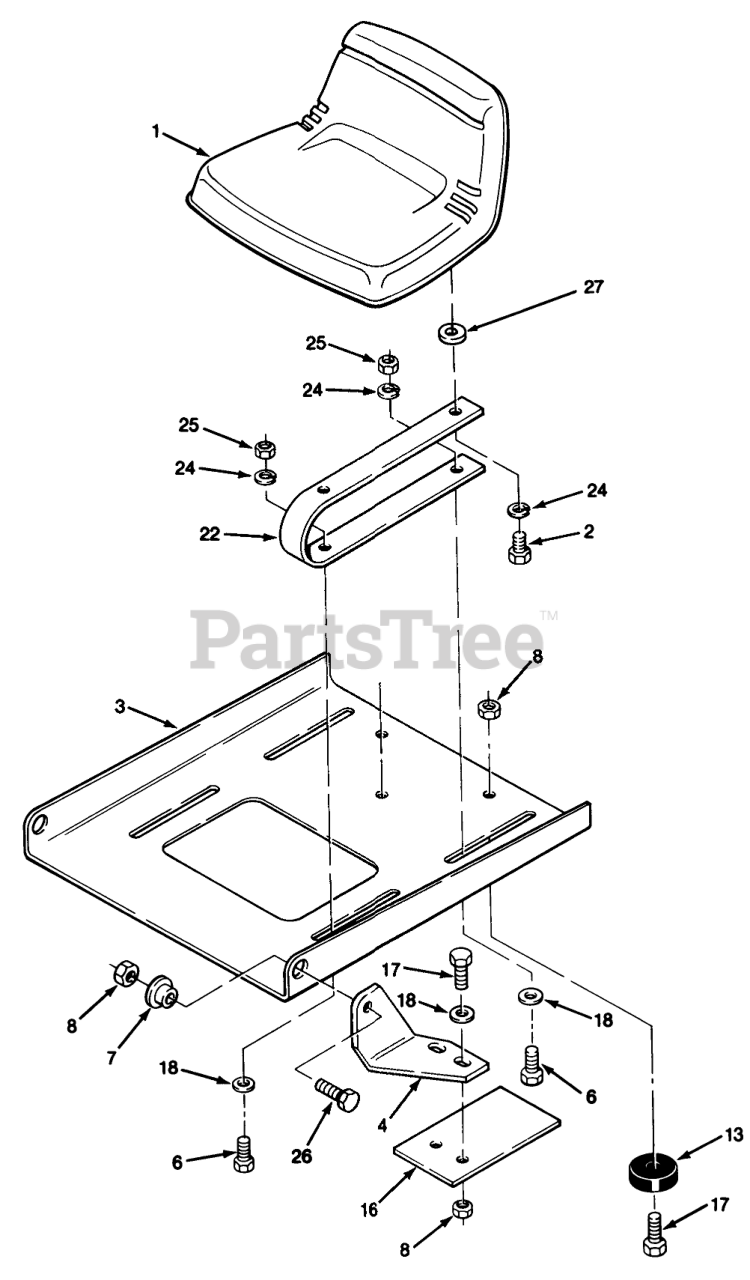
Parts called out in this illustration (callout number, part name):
1	SEAT V-510
2	SCREW-HH
3	PLATE-SEAT PIVOT B
4	BRACKET-PIVOT L.H B
6	SCREW-HH
7	BUSHING
8	NUT-LOCK, NI
13	BUMPER
16	PLATE R
17	SCREW-HH
18	WASHER-PLAIN
22	SPRING-SEAT B
24	WASHER-LOCK
25	NUT-HEX
26	SCREW-HH
27	SPACER-NYLON
